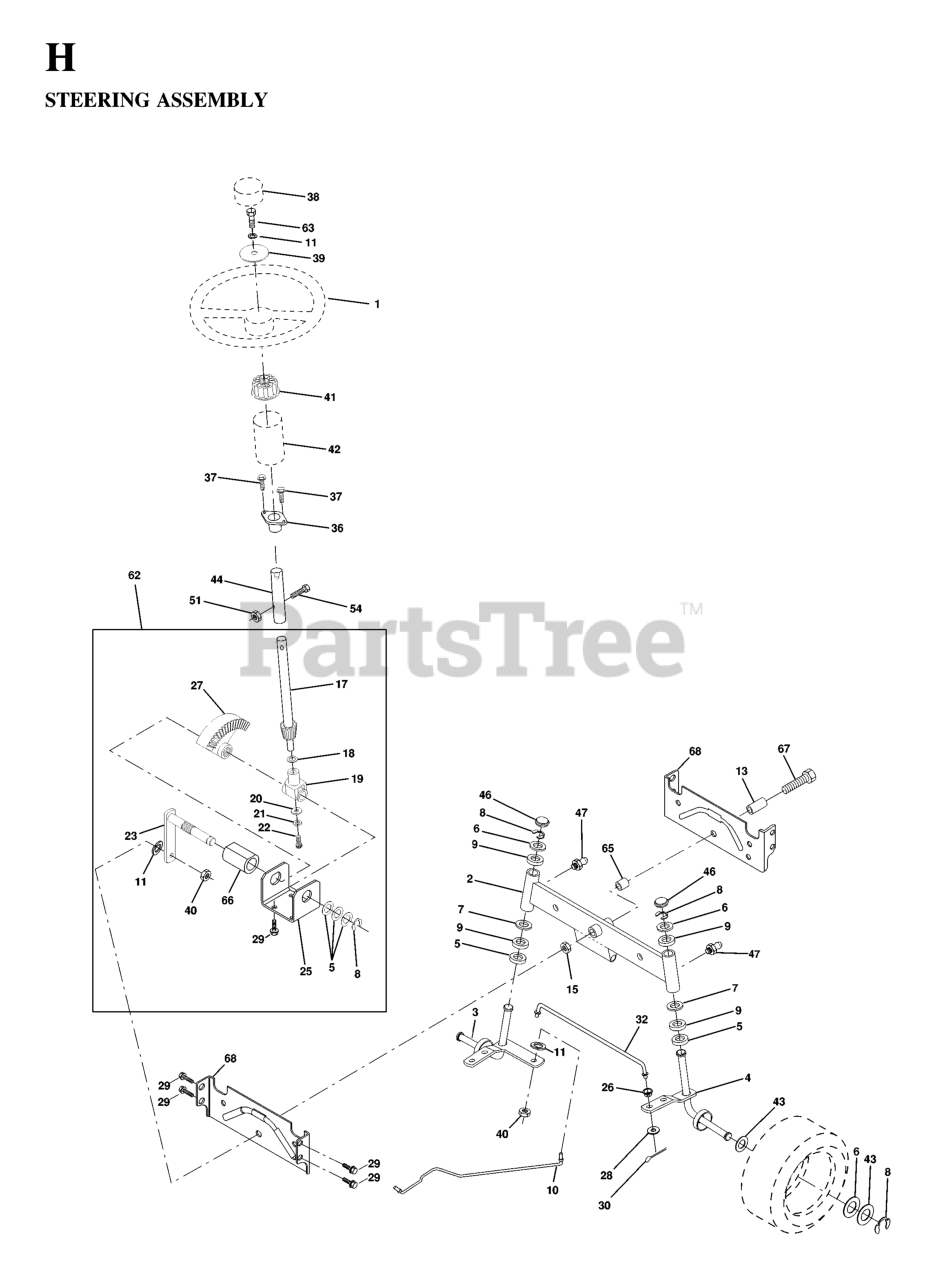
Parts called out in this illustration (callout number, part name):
1	STEERING WHEEL
2	AXLE ASSY
3	SPINDLE.ASM.LH
4	SPINDLE ASM, RH
5	THRUST WASHER
9	BRNG T
10	DRAGLINK-STAMPED
11	WASHER, LOCK 3/8
13	BEARING AXLE
15	NUT-LOC,FLANGE LT
17	SHAFT ASM STEERING
18	THRUST WASHER
19	SHAFT,SUPPORT
20	WASHER
21	LOCKWASHER
22	SCREW
23	SHAFT PITMAN
25	BRACKET STEERING
26	BUSHING.DRAGLINK (2 2)
27	GEAR.SECTOR
28	WASHER
29	SCREW
30	COTTER PIN
32	TIE ROD
36	BUSHING, STEERING
37	SCREW.TT.#10-32X.5.3/8.FLANGE
38	INSERT,STR WHEEL
39	WASHER T
40	GRIPCO NUT
41	ADAPTER LT
42	BOOT, STEERING
44	EXT SHAFT STEERING
46	CAP.SPINDLE.BLACK
47	ZERK M
51	NUT.71038.31-18.HEX.NYLOCK
54	BOLT.5/16-18X1-1/4 FULL.THREAD
62	KIT, STEERING ASSEMBLY
65	SPACER AXLE
66	BEARING ARM
67	Bolt, Hex 5/8 -11 x 2 - 3/4 Gr. 5
68	AXLE, BRACE
